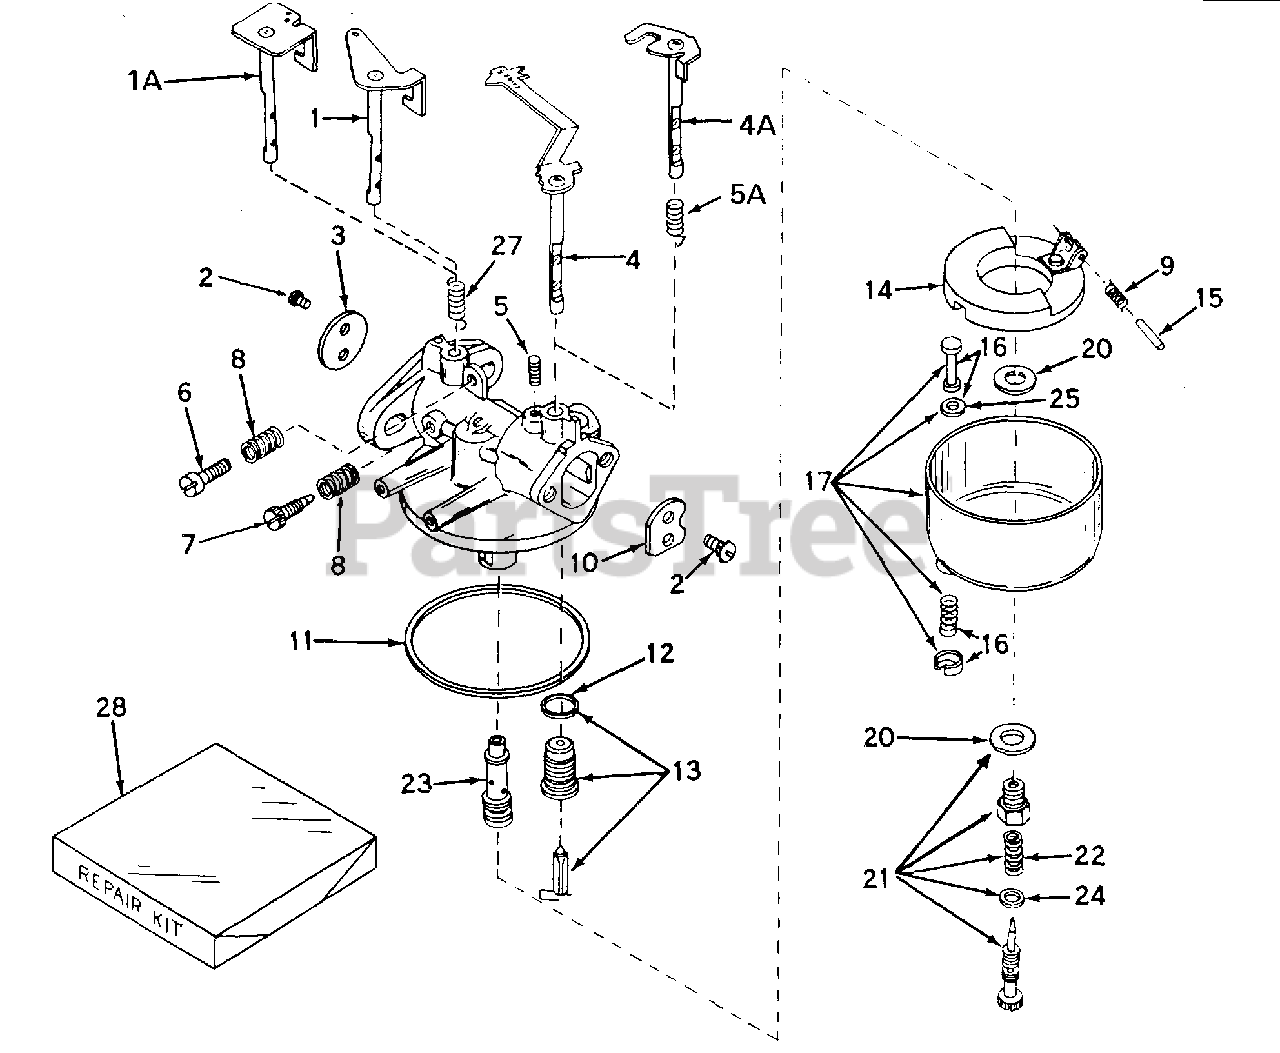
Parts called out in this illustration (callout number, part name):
1	Throttle Shaft & Lever Assembly
2	Screw
3	Throttle Shutter
4	Choke Shaft & Lever Assembly
5	Choke Stop Spring
6	Throttle Adjusting Screw
7	* Idle Adjusting Needle
8	Adjusting Needle Spring
9	Float Shaft Spring
10	Choke Shutter
11	* Bowl-to-Body Gasket
12	Valve Seat Gasket
13	* Valve, Seat, Gasket & Spring Assy. In cl. 9,12
15	* Float Shaft
16	Bowl Drain Assembly (Incl. 25)
17	Bowl & Drain Assembly (Incl. 16)
20	* Bowl-to-Body Gasket
21	* Power Adjusting Needle Ass'y. Incl. 2 0,22,24
22	Adjusting Needle Spring
23	Main Nozzle
24	"O" Ring
25	Drain Stem Gasket
27	Throttle Return Spring
28	Repair Kit (Incl. items marked PK in notes) Incl. (1) each of part #'s271 06, 27109, 27110, 27112, 32255A,63163 8
